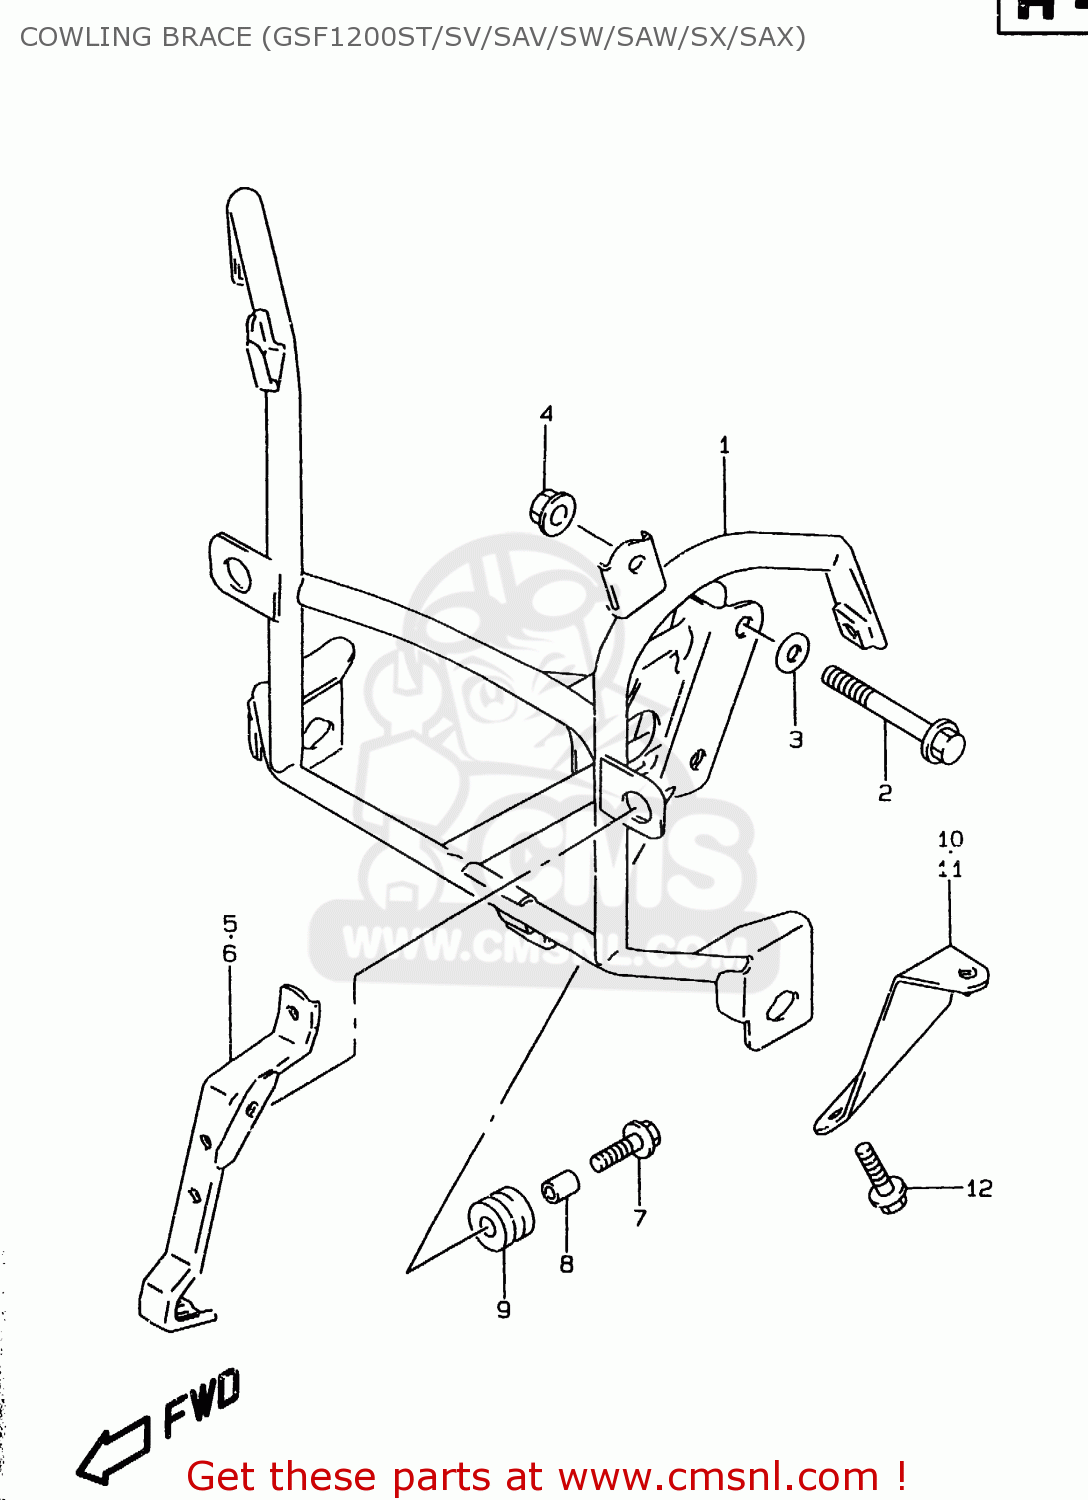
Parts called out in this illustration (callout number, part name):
1	BRACE,COWLING
2	BOLT(8X40)
3	WASHER
4	NUT
5	BRACKET,HEADLAMP,R
6	BRACKET,HEADLAMP,L
7	BOLT(6X25)
8	SPACER(6.5X9X10)
9	CUSHION
10	BRACKET,COWLING RR,R
11	BRACKET,COWLING RR,L
12	BOLT
